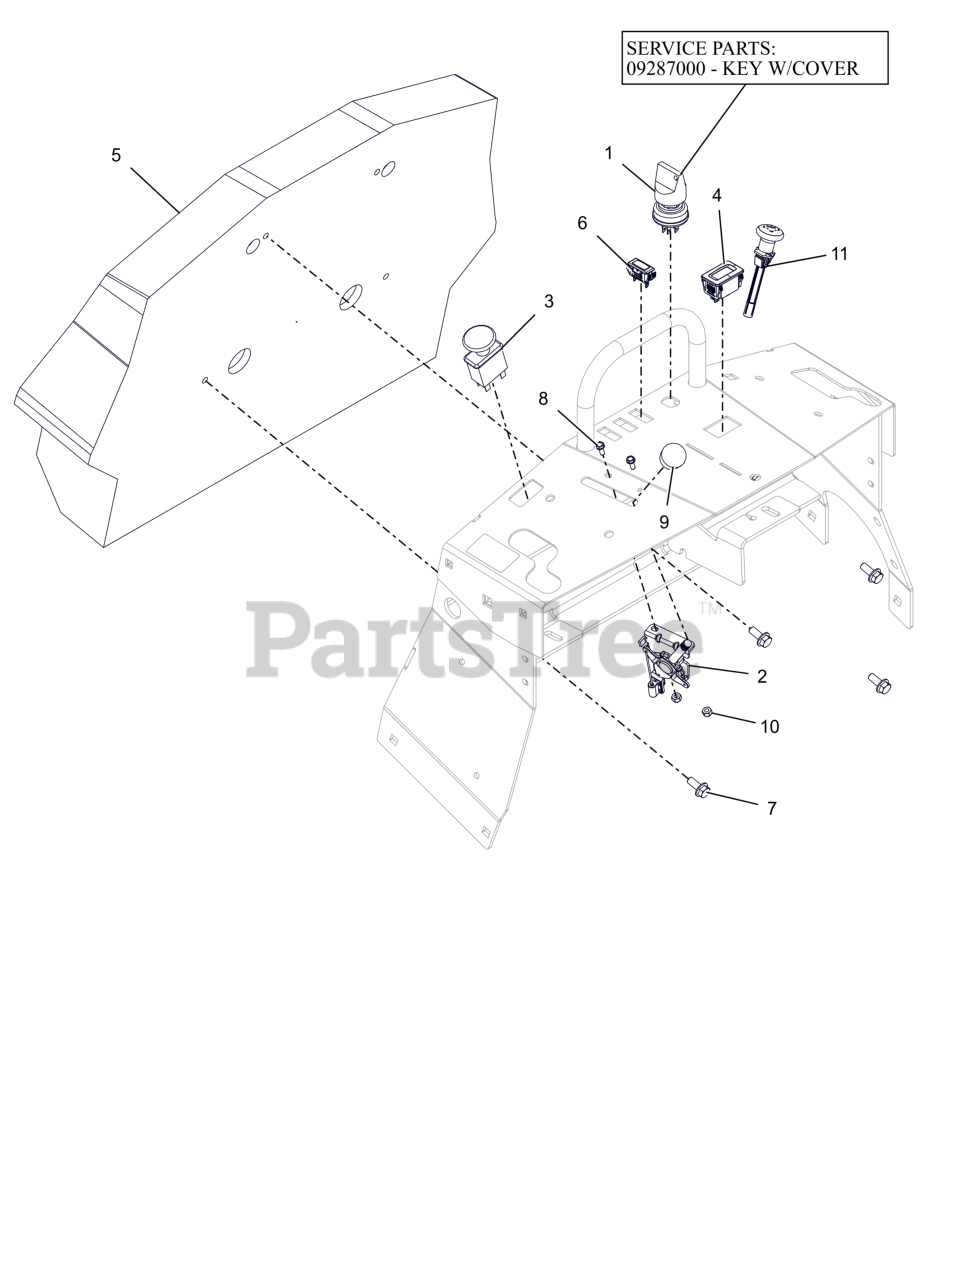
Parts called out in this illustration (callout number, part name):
1	SWITCH, IGNITION
2	CABLE, PROSTANCE - CONTROL 43"
3	SWITCH, CLUTCH
4	HOUR METER
5	PAD, OPERATOR - PROSTANCE
6	LIGHT,INDICATOR
7	BLT, SERHFWH 0.312-18X0.75 GR5 ZCC
8	BLT, HWH #10-24X.50 ZCC
9	KNOB-CONTROL-BLACK .38-16X.50
10	NUT-LK-NYL #10-24 G2 ZCC
11	CABLE, CHOKE (SNAP IN)
